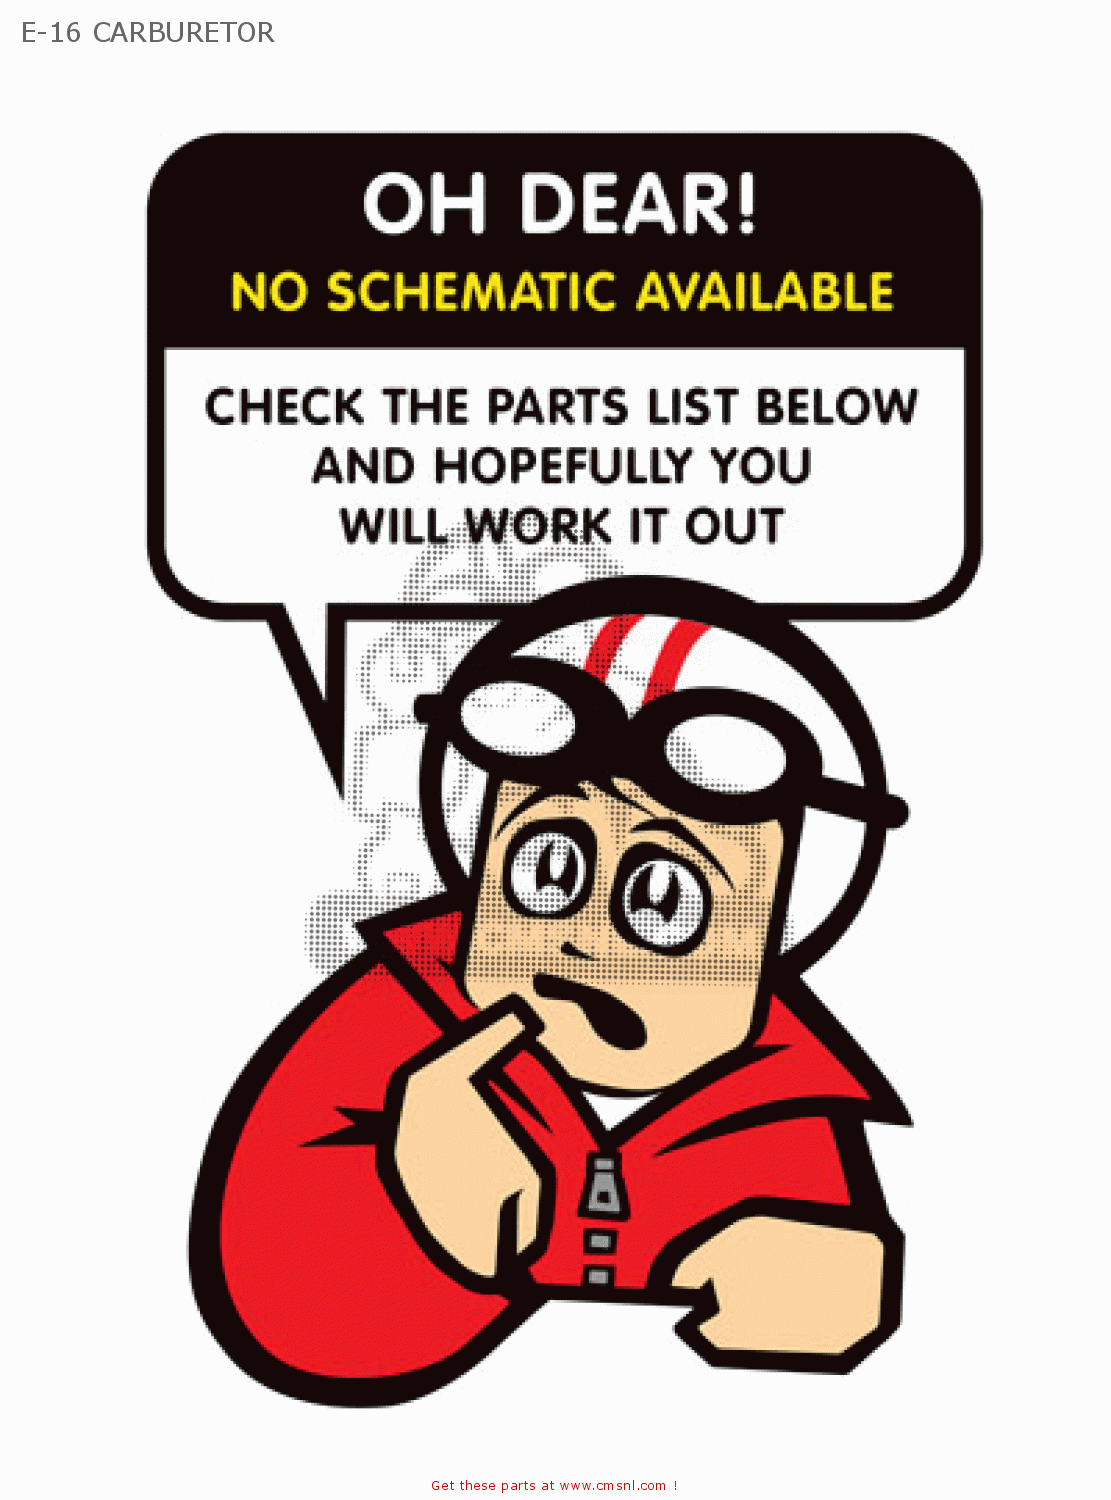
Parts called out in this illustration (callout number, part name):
1	GASKET,CYLINDER (NAS)
2	SEAL,VALVE STEM
3	GASKET,CYLN.HEAD (NAS)
4	PACKING,TAPPET (NAS)
5	GSKT,CYLN.STUD (NAS)
6	GASKET,EX.PIPE (NAS)
7	O-RING,32X2.7
8	O-RING,78.3X2
9	O-RING,7.7X2.5
